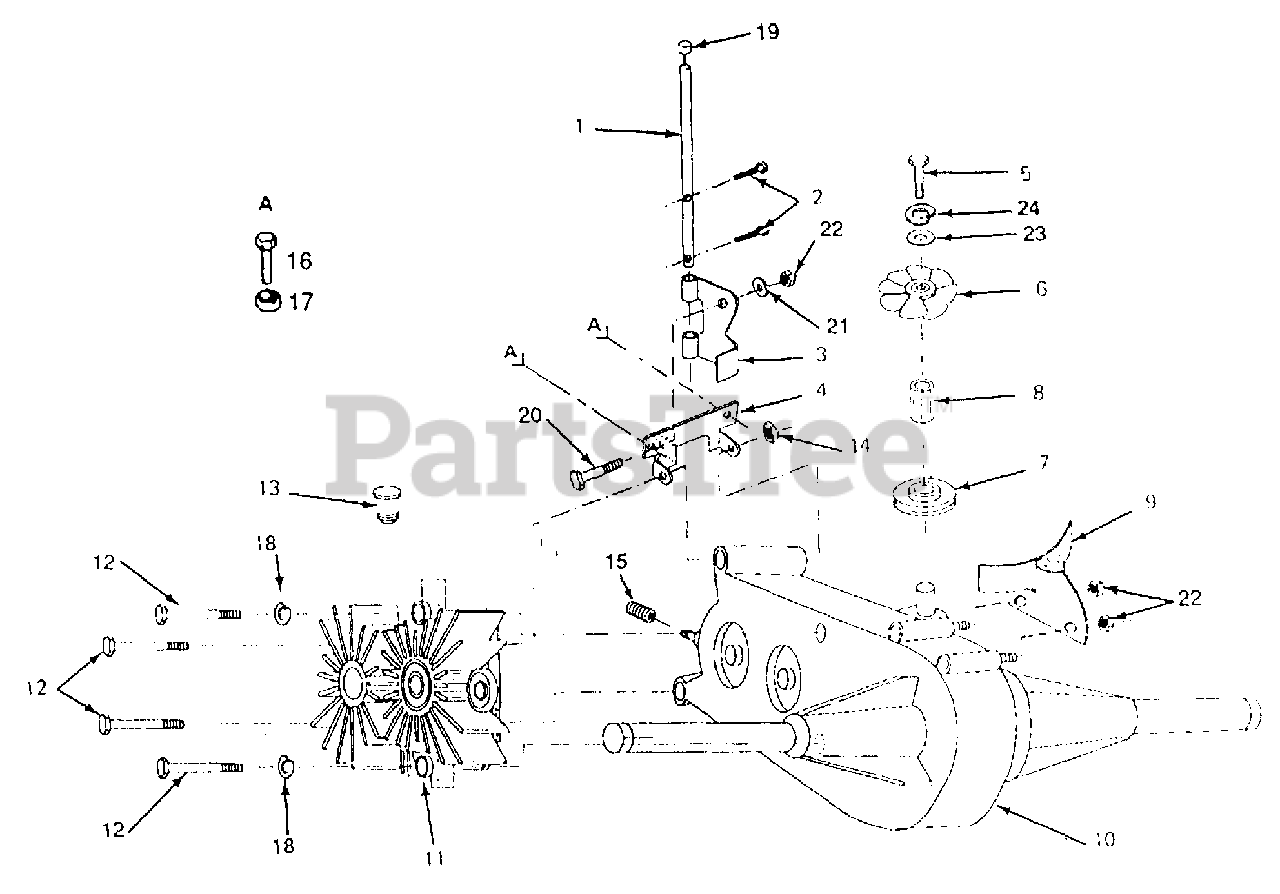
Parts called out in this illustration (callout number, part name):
1	Rod, Free Wheel Control
3	Control, Coast
4	Bracket, Pnt. Mounting Differential
6	Fan, Hydro 8"
7	Pulley, Transaxle
8	Standoff, Fan Hydro
9	Guard Assembly, Belt
10	Differential Assembly
11	Pump Assembly
13	Reservoir Pump
15	Spring, Compression
17	Nut 3/8 - 16 UNC
18	Lockwasher
19	Cap
20	Bolt shoulder 1/4 - 20 UNC
21	Washer, nylon
22	Nut, Crown lock 1/4 - 20 UNC
23	Washer 9/32 x 1 - 1/4 x 16 ga.
